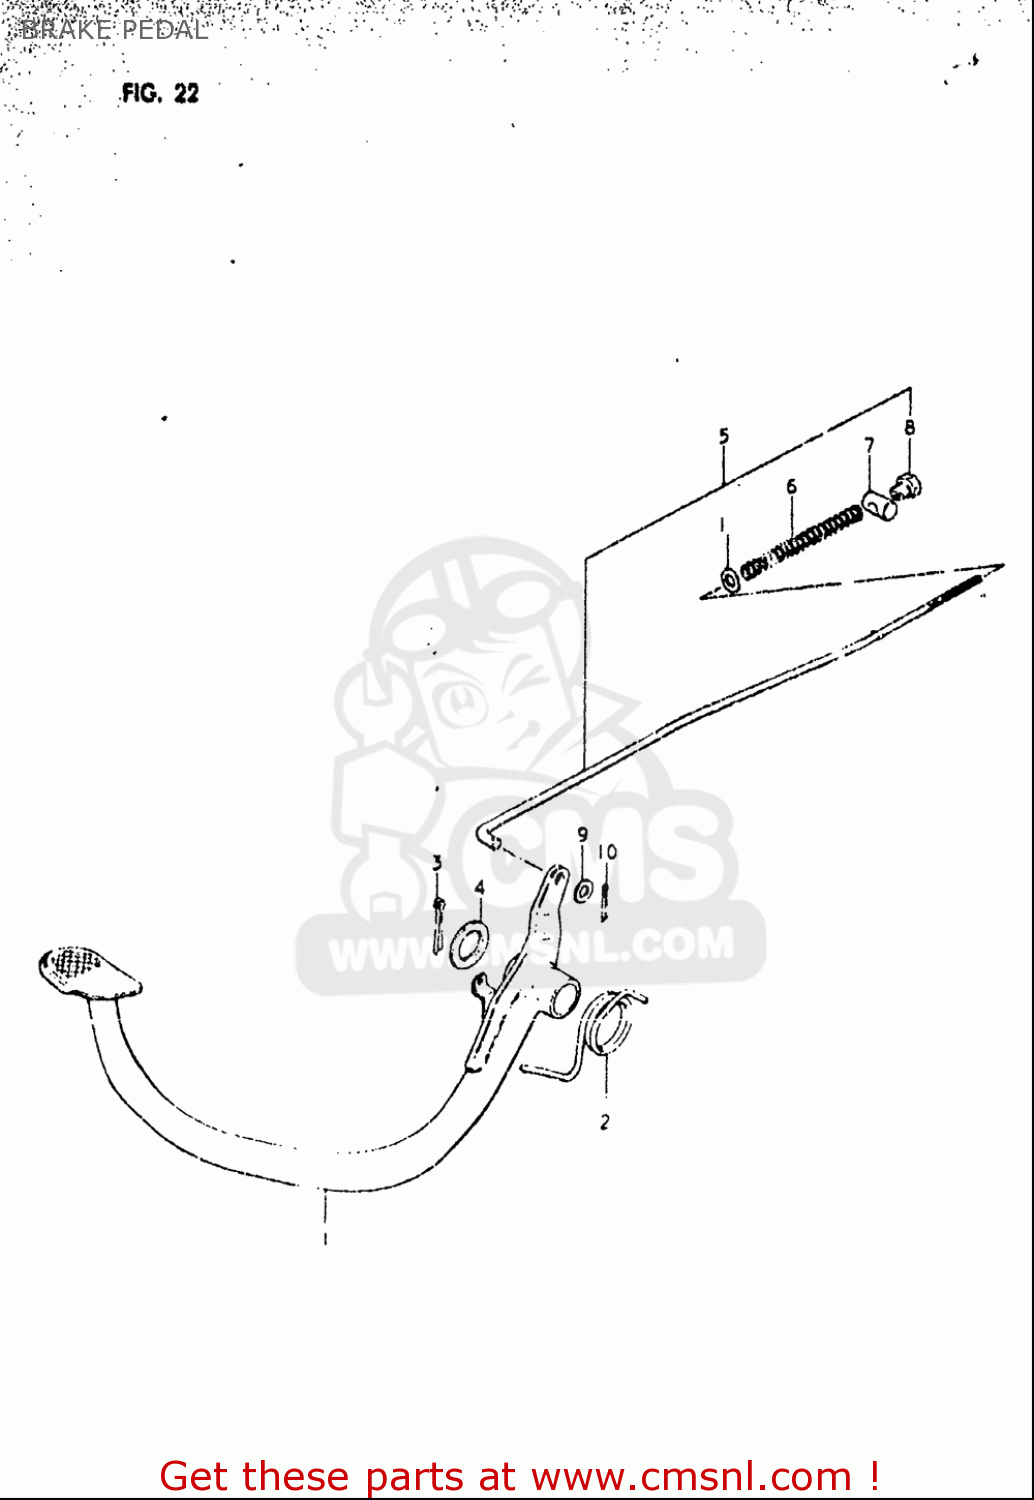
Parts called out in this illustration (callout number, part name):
3	PIN
4	WASHER(15.5X26X2.3)
5	ROD ASSEMBLY,REAR BRAKE
6	SPRING
7	PIN(11X18)
8	NUT
9	WASHER
10	PIN
11	WASHER
